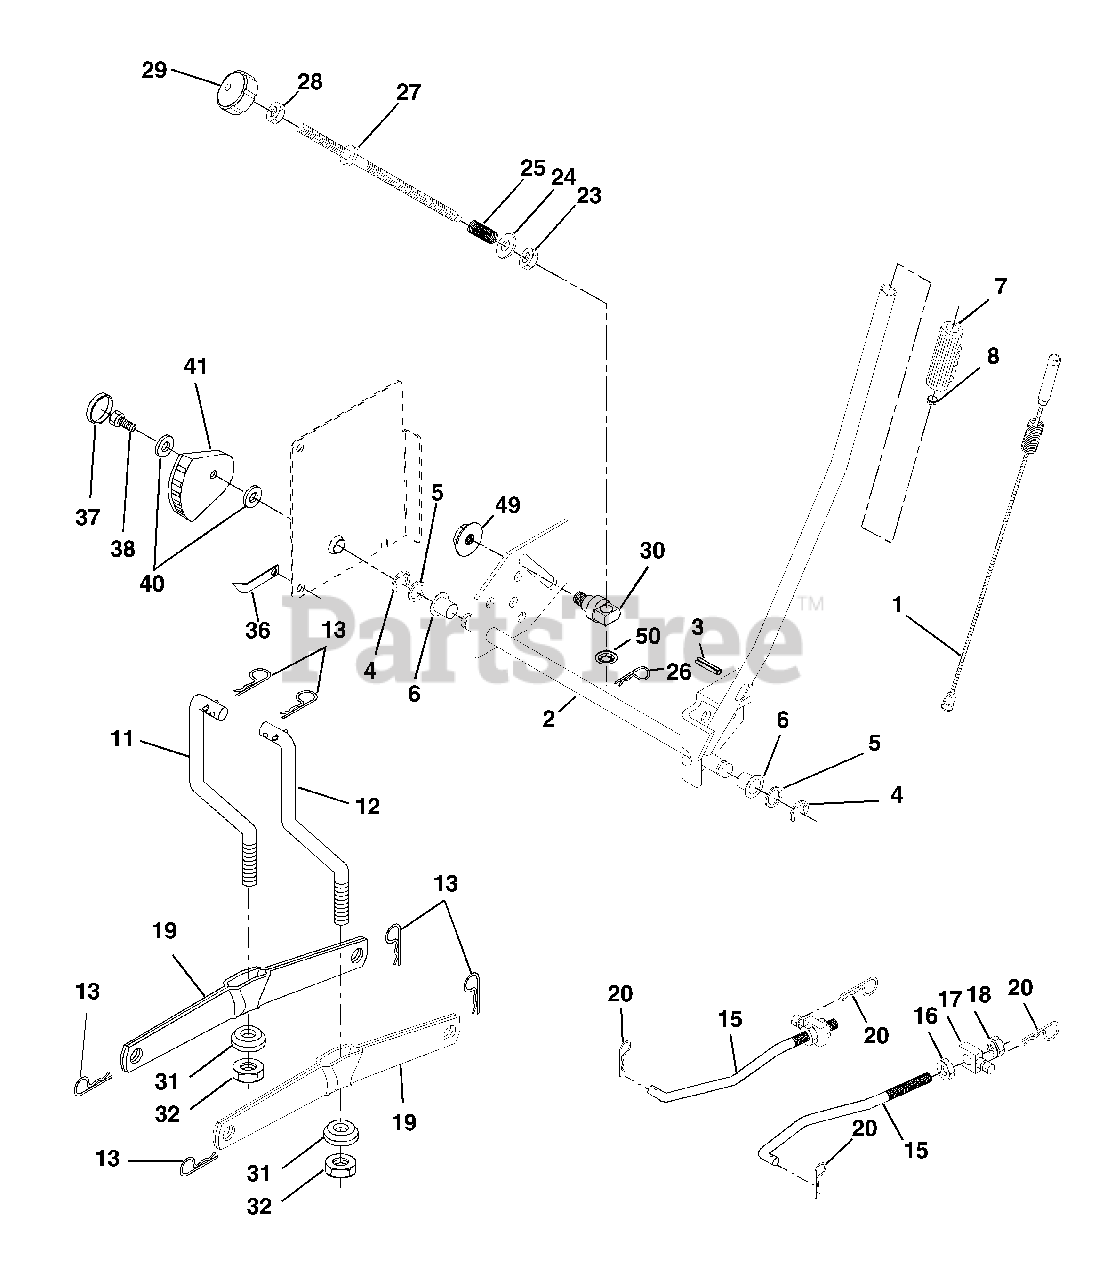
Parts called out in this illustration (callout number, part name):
1	Wire Asm Inner/Spring W/Plunger LT
2	Shaft Asm Lift RH w/Inf
3	Pin Groove 1 500 Zinc
4	E Ring #5133-62
5	Washer 21/32 X 1 X 21 Ga
6	Bearing Nylon Blk 629 Id
7	Grip Handle Fluted Blk
8	Button Plunger Black
11	Link Lift LH Fixed Length
12	Link Lift RH Fixed Length
13	Retainer Spring
15	Link Front
16	Nut Jam Hex 1/2-13 Unc
17	Trunnion Blk Zinc
18	Nut Lock w/Wsh 1/2-13unc
19	Arm Suspension Rear
20	Retainer Spring
23	Nut
24	Washer 13/32 X 5/8 X 16 Ga
25	Spring 2-1/8"
26	Retainer Clip
27	Rod Adj Lift Zinc 7.49 Wrk Lg
28	Nut Hex Jam 3/8-16 Unc
29	Knob Inf 3/8-16 Unc Blk W/sym
30	Trunnion Infin Height
31	Bearing Pvt Lift
32	Nut Crownlock 3/8 - 24
36	Indicator Height STLT
37	Plug Hole Blk 1.485/1.515 Dia.
38	Screw 5/16-18 x 1
40	Washer 11/32 x 1-1/2 10 Ga.
41	Scale Ind. Height Blk.
49	Nut Hex Flange Lock
50	Nut, Push Phos & Oil
